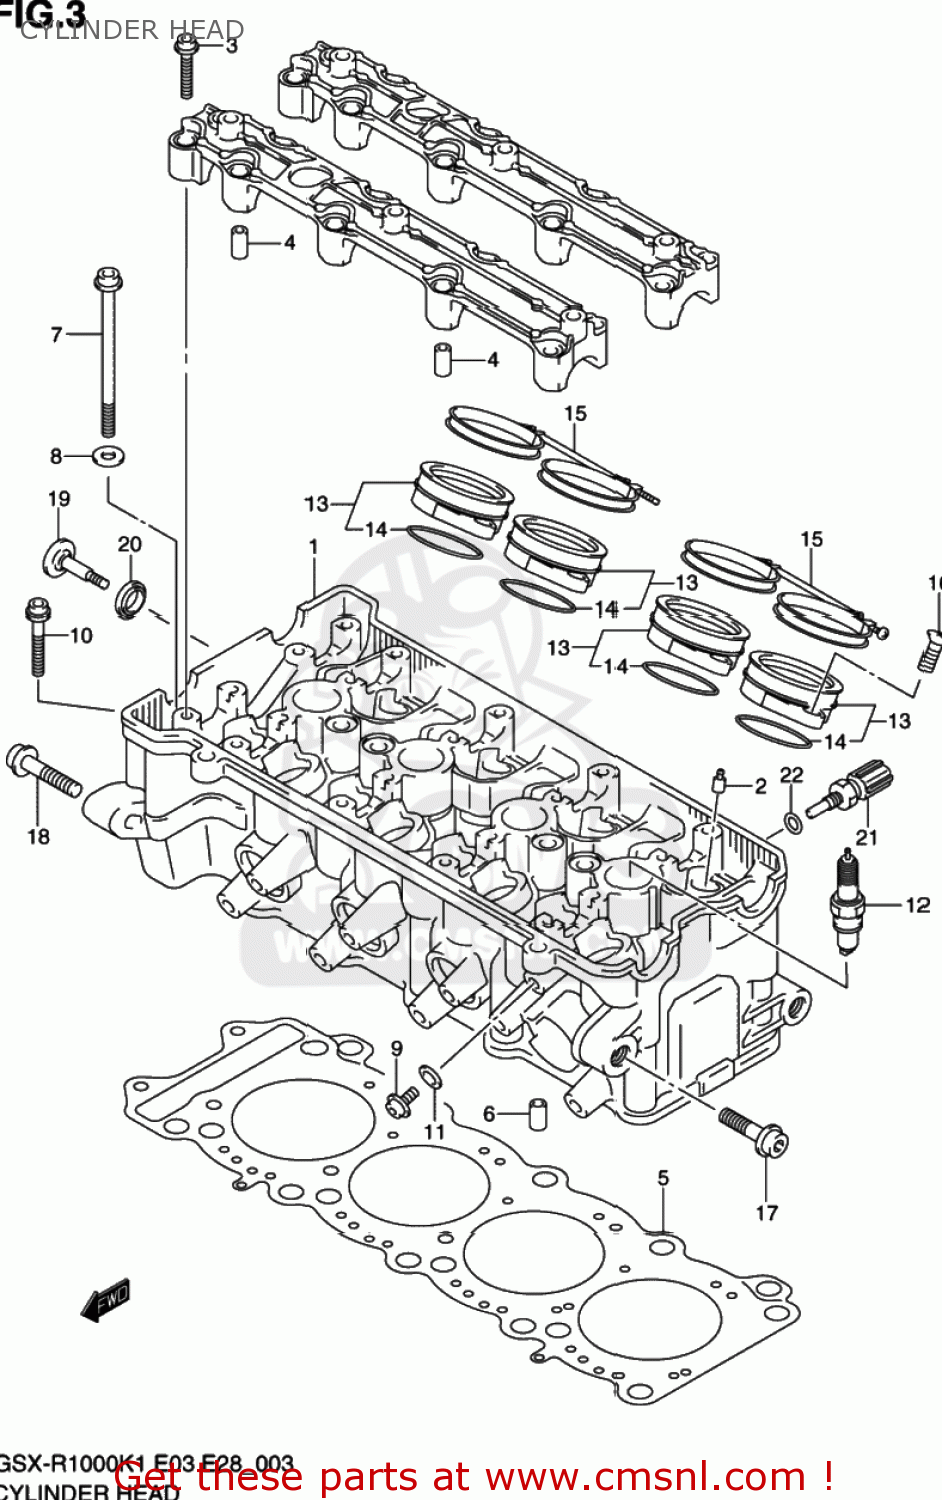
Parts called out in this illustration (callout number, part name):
1	HEAD ASSY,CYLINDER
2	GUIDE,VALVE
3	BOLT
4	PIN(6.2X8X16)
5	GASKET,CYLINDER HEAD (NAS)
6	PIN
7	BOLT(10X105)
8	WASHER(10.5X19X2)
9	BOLT
10	BOLT,CYL.OIL P
11	GASKET(5.8X13X1.2) (NAS)
12	PLUG,SPARK(CR8E)
13	PIPE ASSY,INTAKE
14	O RING(D:2.4,ID:47X42)
15	CLAMP,INTAKE PIPE
16	SCREW ,6X16
17	BOLT(10X45)
18	BOLT(10X55)
19	BOLT,CYL HEAD SIDE FACE
20	WASHER,HEAD COVER
21	SENSOR,WATER TEMP
22	GASKET(12X17X1) (NAS)
